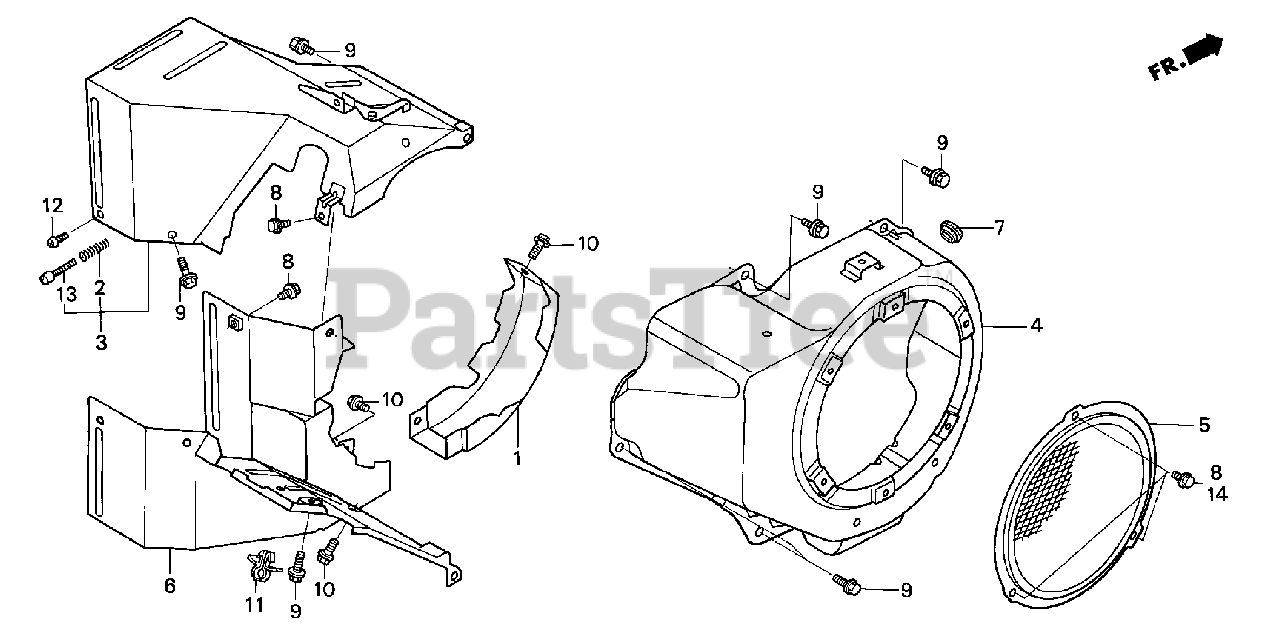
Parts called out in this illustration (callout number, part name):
1	SCROLL, ALTERNATOR FAN
2	SPRING, CONTROL ADJUSTING
3	SHROUD ASSY. (UPPER)
4	COVER, FAN
5	PROTECTOR, FAN COVER
6	SHROUD (LOWER)
7	GROMMET, DRAIN HOLE
8	BOLT, FLANGE (6X8)
9	BOLT, FLANGE (6X12) (CT200)
10	BOLT, FLANGE (5X10)
11	CLIP, WIRE HARNESS (6MM) (WHITE)
12	SCREW, PAN (5X8)
13	SCREW, PAN (5X32)
14	BOLT, FLANGE (6X10)
